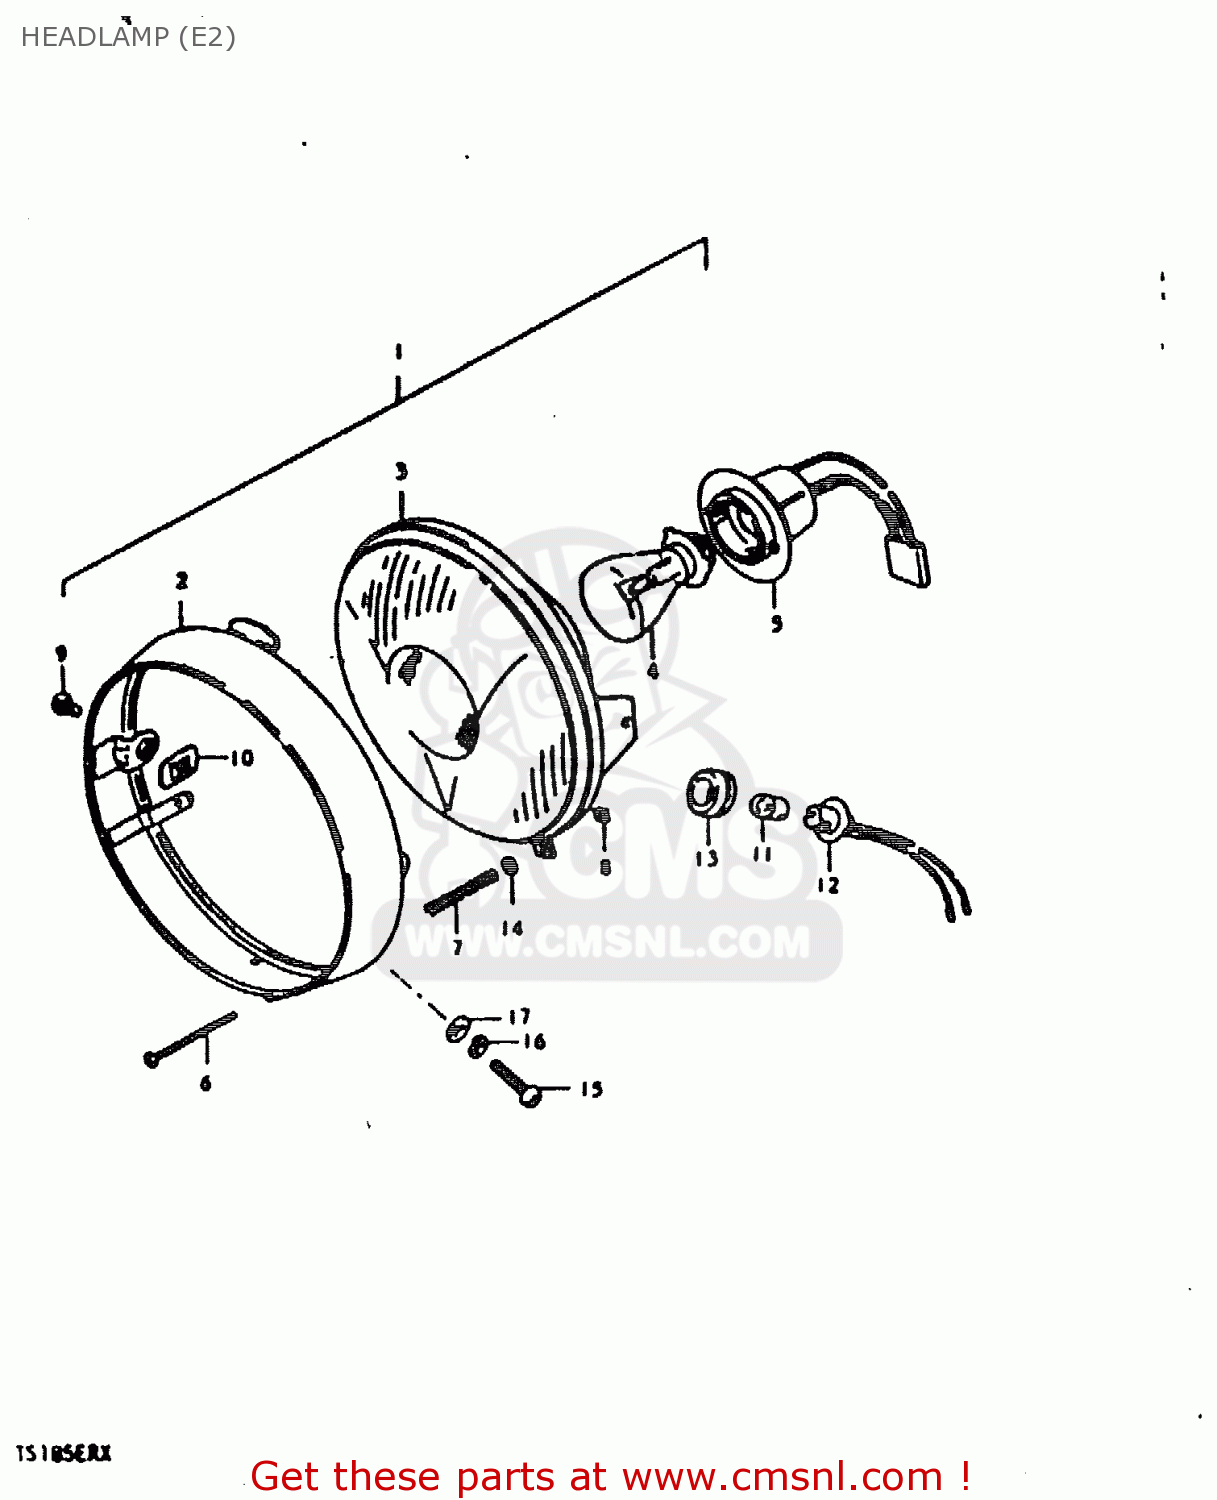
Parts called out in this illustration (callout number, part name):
1	HEADLAMP ASSY
2	RIM
3	UNIT
4	BULB(6V25/25W,STANLEY,A7007)
5	SOCKET
6	SCREW,HEADLAMP ADJUST
7	SPRING
8	NUT,HEADLAMP ADJUSTER
9	SCREW
10	NUT
11	BULB(6V/3W)
12	SOCKET
13	RUBBER
14	WASHER
15	SCREW
16	LOCK WASHER
17	WASHER
